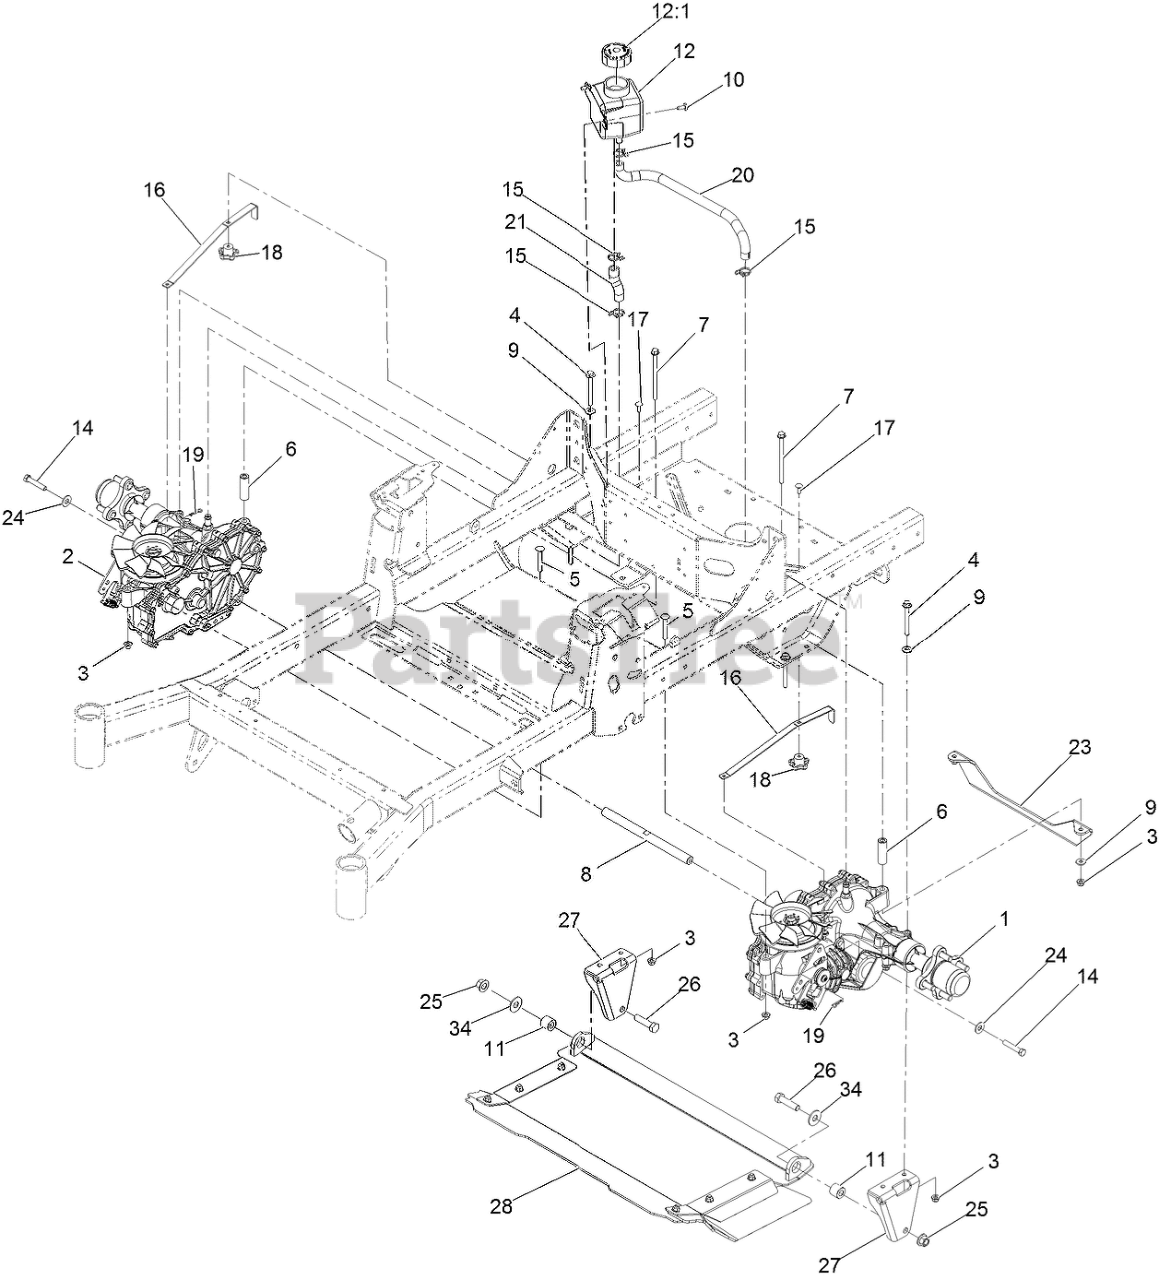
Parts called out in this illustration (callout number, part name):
1	LH TRANSAXLE ASM
2	RH TRANSAXLE ASM
3	NUT-HF, NI
4	SCREW-HHF
5	BOLT-CARR
6	SPACER-HYDRO
7	SCREW HHF
8	SHAFT-SPACER
9	WASHER-SPRING
10	SCREW-TORX
11	BUSHING-SLEEVE
12	TANK-HYD
12:1	CAP-RESERVOIR, HYD
14	SCREW-HH W/LOCTITE
15	CLAMP-HOSE
16	ARM-BYPASS, HYDRO
17	BOLT-CARR
18	KNOB-HANDLE
19	PIN-COTTER
20	HOSE-HYDRAULIC
21	HOSE-HYDRAULIC
23	SUPPORT-TRANSMISSION
24	WASHER-FLAT
25	Nut-Lock 1/2-13
26	SCREW-HH
27	BRACKET-MOUNT, DISCHARGE
28	DISCHARGE TUNNEL ASM
34	WASHER-FLAT
